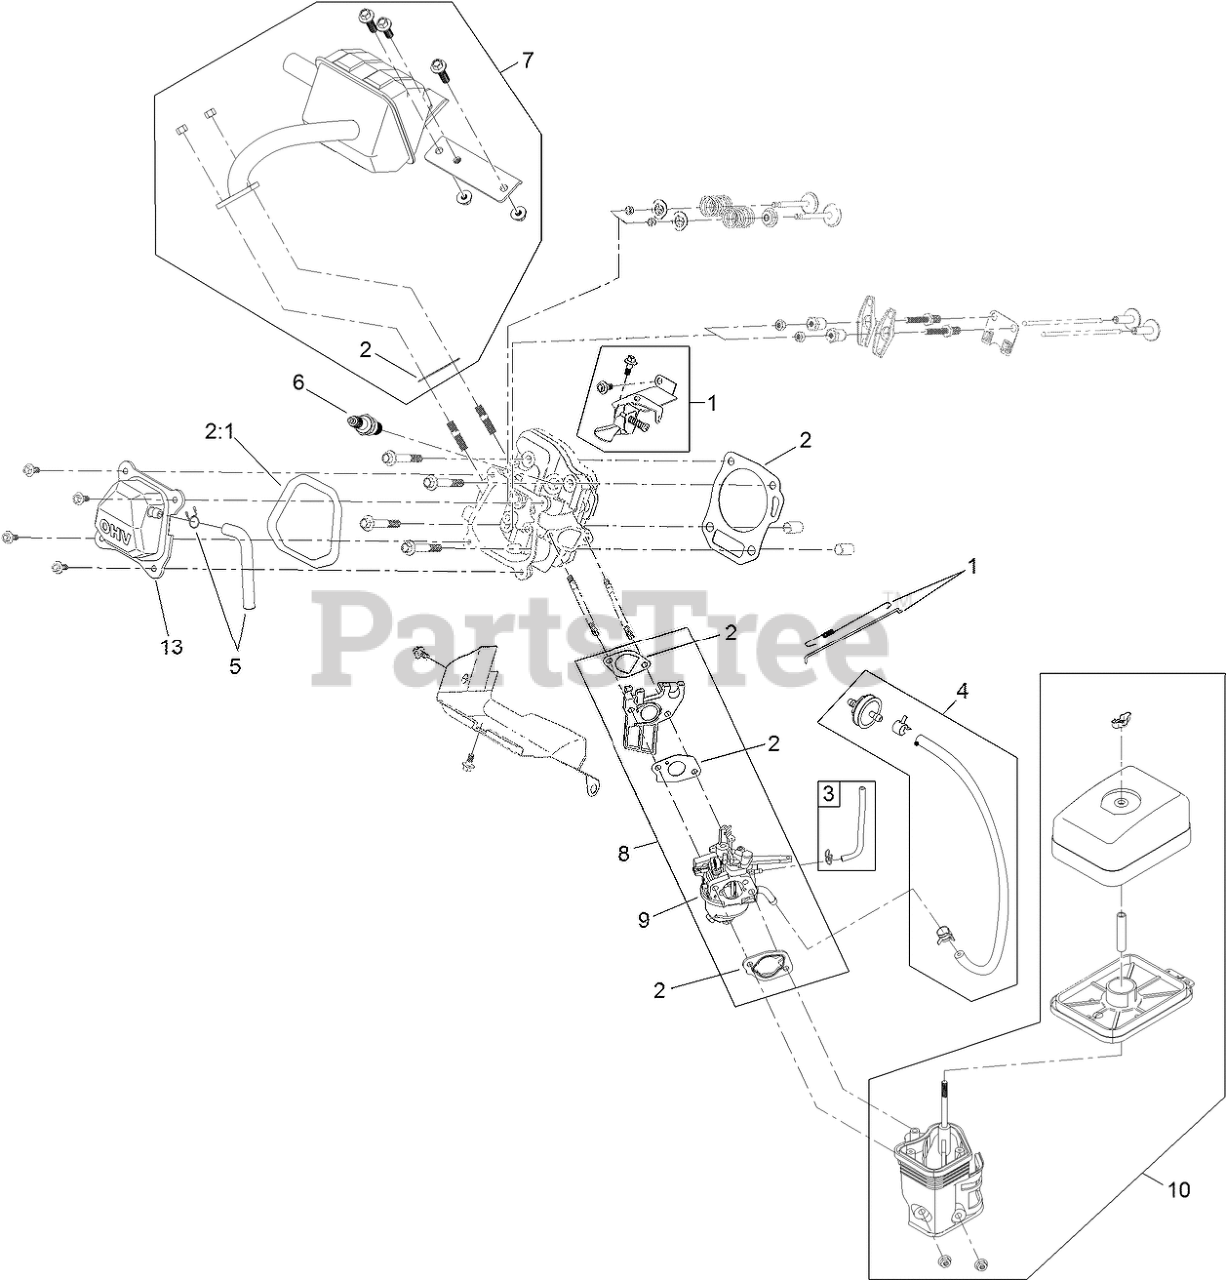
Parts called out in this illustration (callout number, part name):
1	GOVERNOR KIT
2	GASKET AND SEAL KIT
2:1	GASKET-COVER, VALVE
3	PRIMER LINE KIT
4	FUEL LINE KIT
5	BREATHER TUBE KIT
6	PLUG-SPARK
7	MUFFLER KIT
8	COMPLETE CARBURETOR SERVICE KIT
9	CARB REPAIR KIT WITH GASKETS
10	HEATER BOX KIT
13	VALVE COVER ASM
